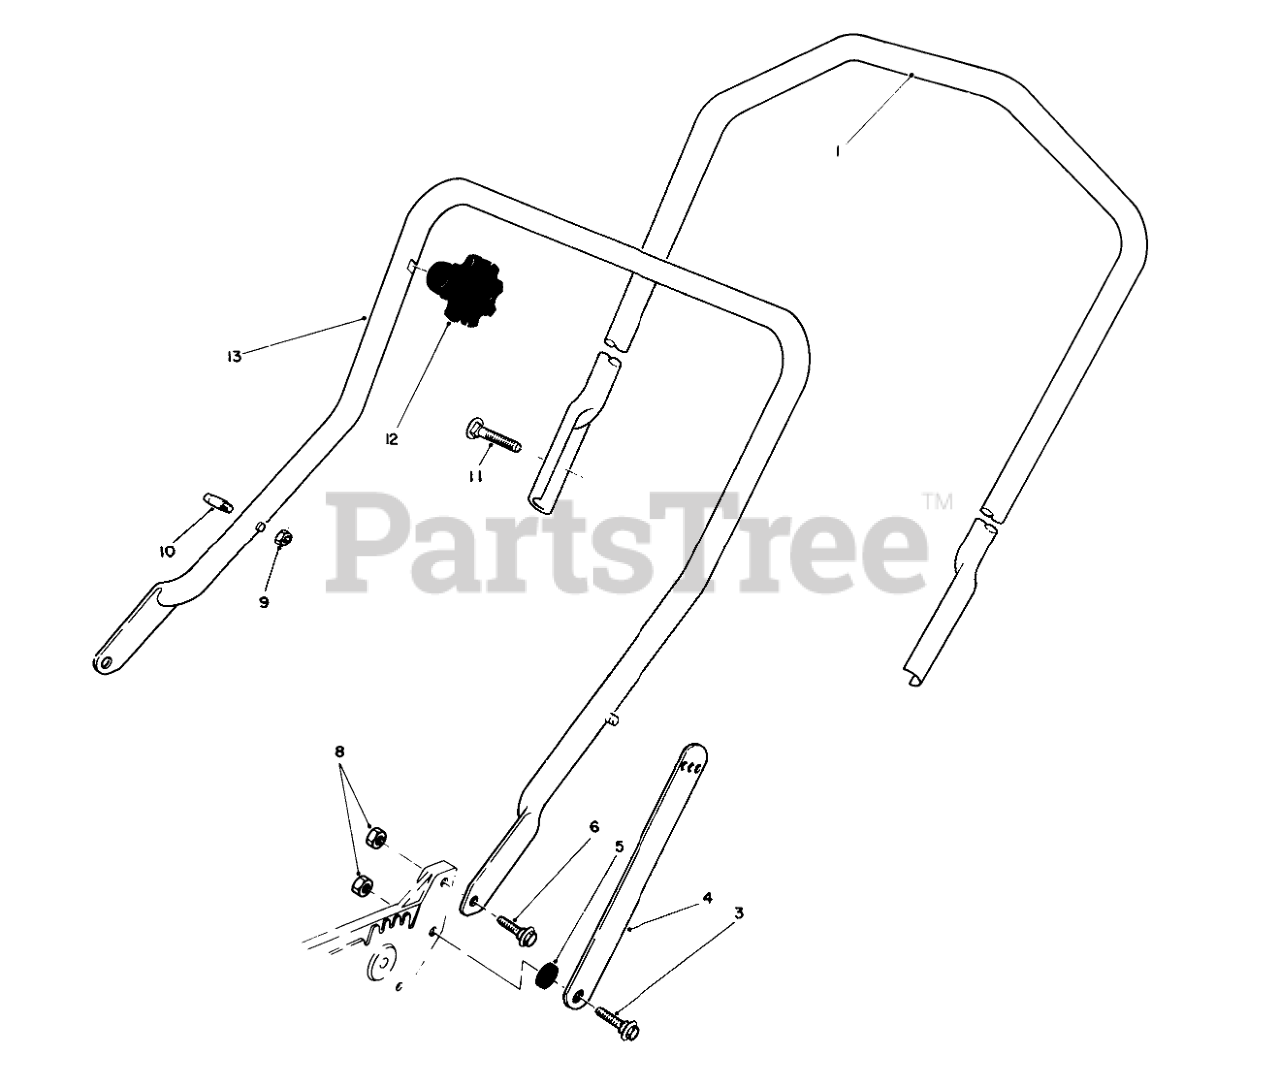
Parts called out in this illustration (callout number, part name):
1	Handle-Upper
3	SCREW-SHOULDER
4	Handle Latch
5	SPACER
6	SCREW-SHOULDER
8	NUT-LOCK, NI
9	NUT-LOCK, NI
10	HANDLE PIN
11	5/16-18 X 2 HNDLE SCREW
13	LOWER HANDLE ASM
